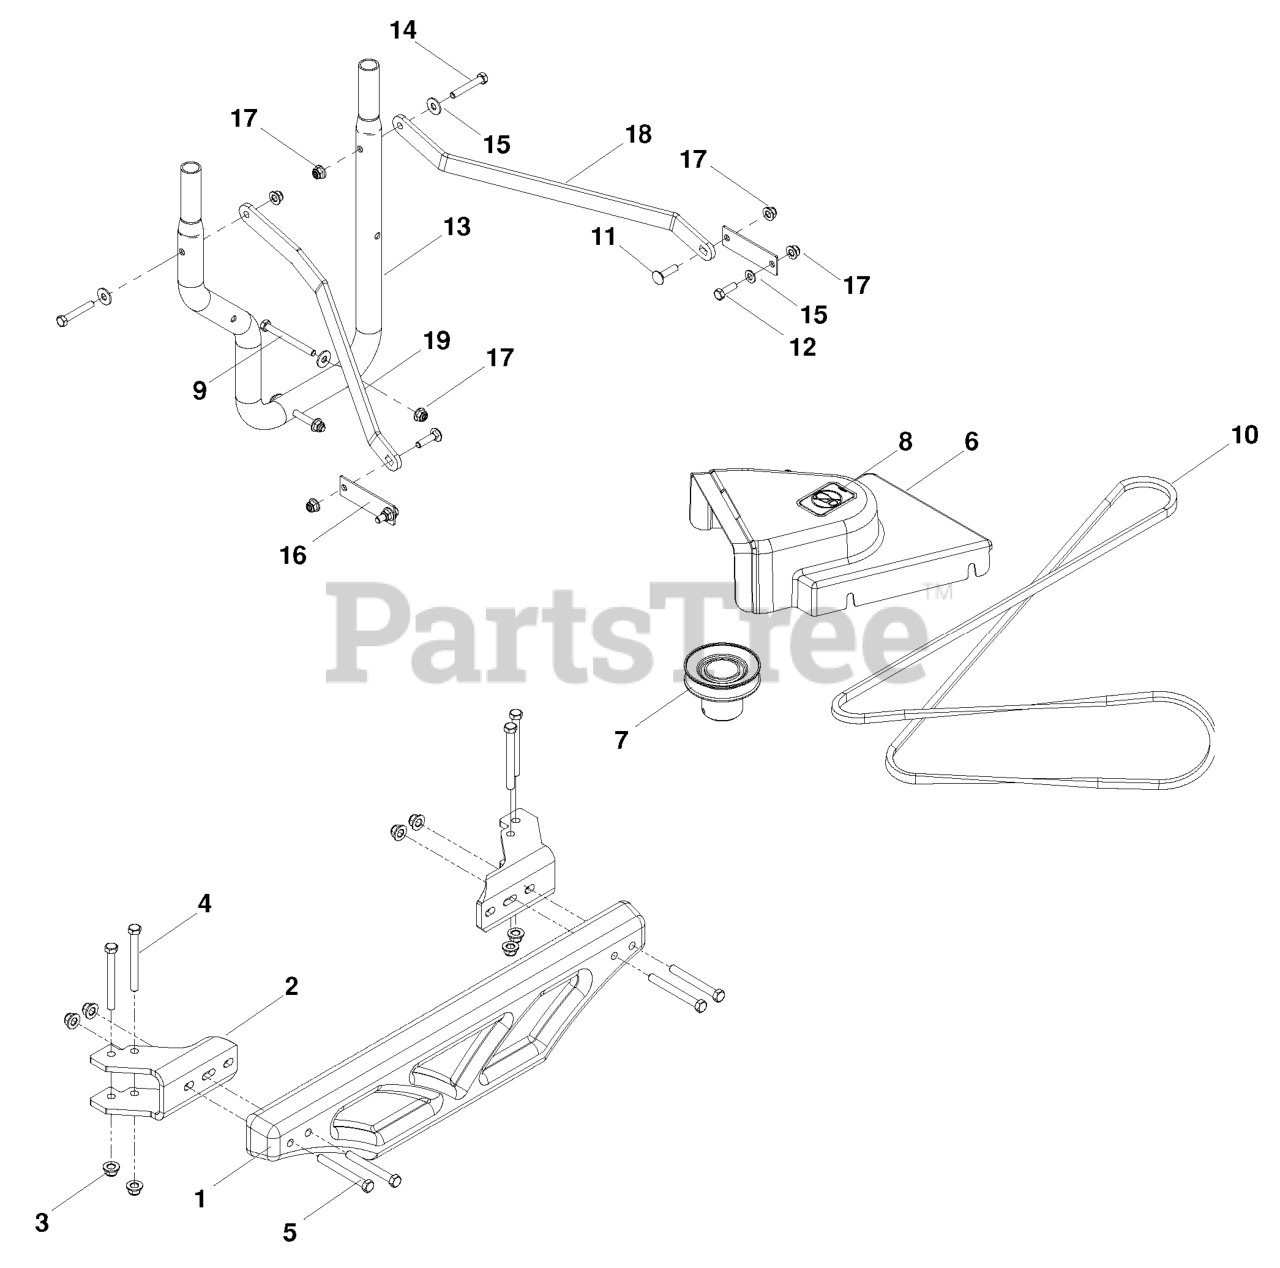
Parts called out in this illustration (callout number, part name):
2	Screen, Cover
3	Frame, Bagger
4	Seal, Cover
5	Gasket, Cover
6	Container, Soft Bag
7	Pin, Hinge
8	Handle, Bagger Cover
9	Support, Hose
10	Flex Trim, Black
11	Plug, Tubing End
12	Plug Spacer
13	Washer 5/16 Sae Flat
14	Hcs 5/16-18 X 11/4
15	Screw #10-24 X 5/8
17	Nut #10-24 Crownlock
18	Nut 5/16-18 Hex Nyloc
19	Screw, Spec 10-14 X 1/2
20	Indicator, Bag Dump
21	Screw 10-24 X 11/8
22	Washer 3/16 X 3/4
23	Spacer, Split
24	Nut, Acorn 10-24
25	Latch, Hood
26	Weld Nut, Plated
27	Chute, Upper
28	Washer 3/16 Lock
29	Chute, Middle
